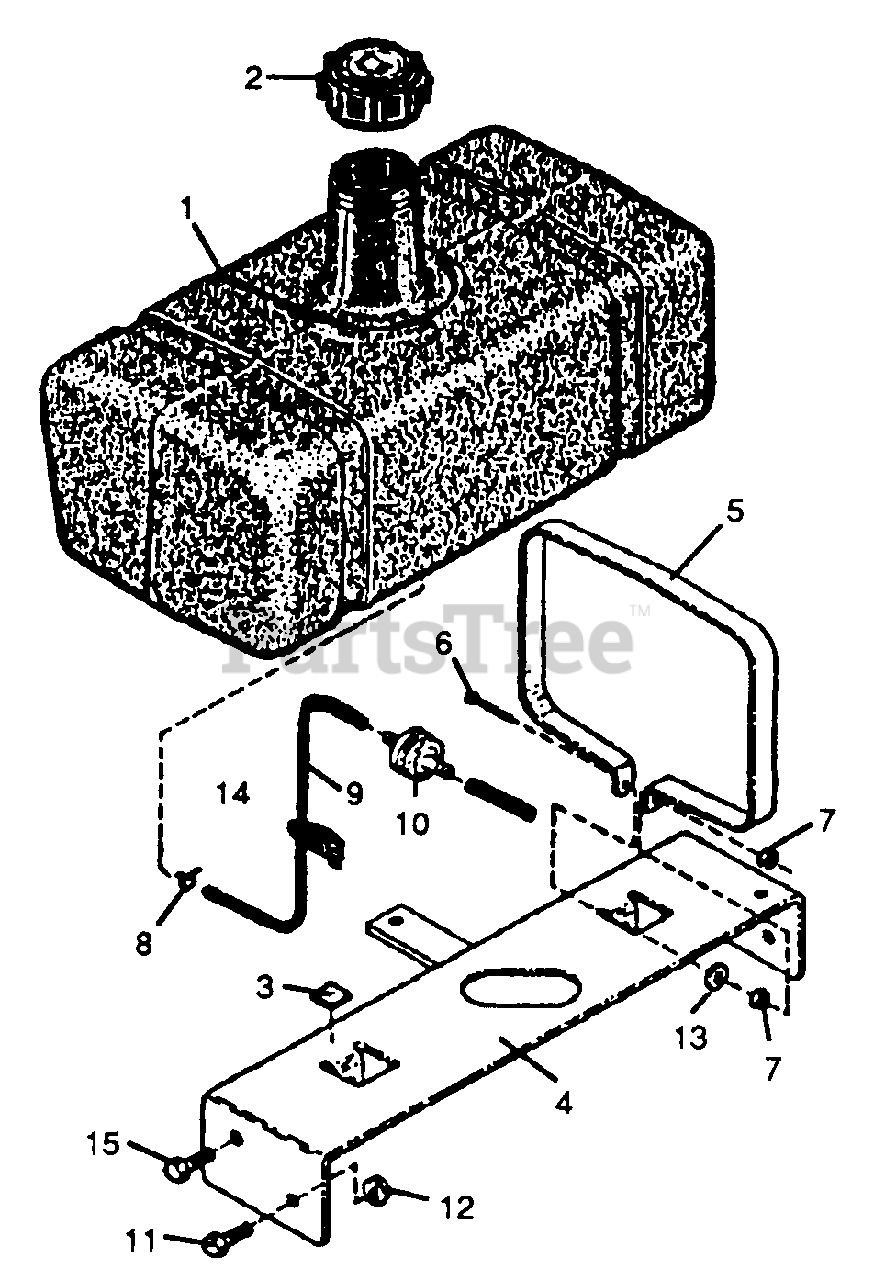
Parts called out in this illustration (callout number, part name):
1	Fuel Tank, 4.2 gal.
2	Fuel Tank Cap
3	Fuel Tank Pad
4	Fuel tank Bracket
5	Fuel Tank Strap
6	#10 - 24 x 1-3/4 Pan Hd. Mach. Saew
7	#10 - 24 Lock Washer & Nut
8	Fuel Line Clamp
9	24- Fuel Line
10	Fuel Filter
11	3/8 -16 x 3/4 Hex. Hd. Cap Screw
12	3/8 -16 Flange Nut
13	#10 Flat Washer
14	Fuel Shut-0ff Valve
15	3/8-16 x 1" Hex. Hd. Cap Screw
